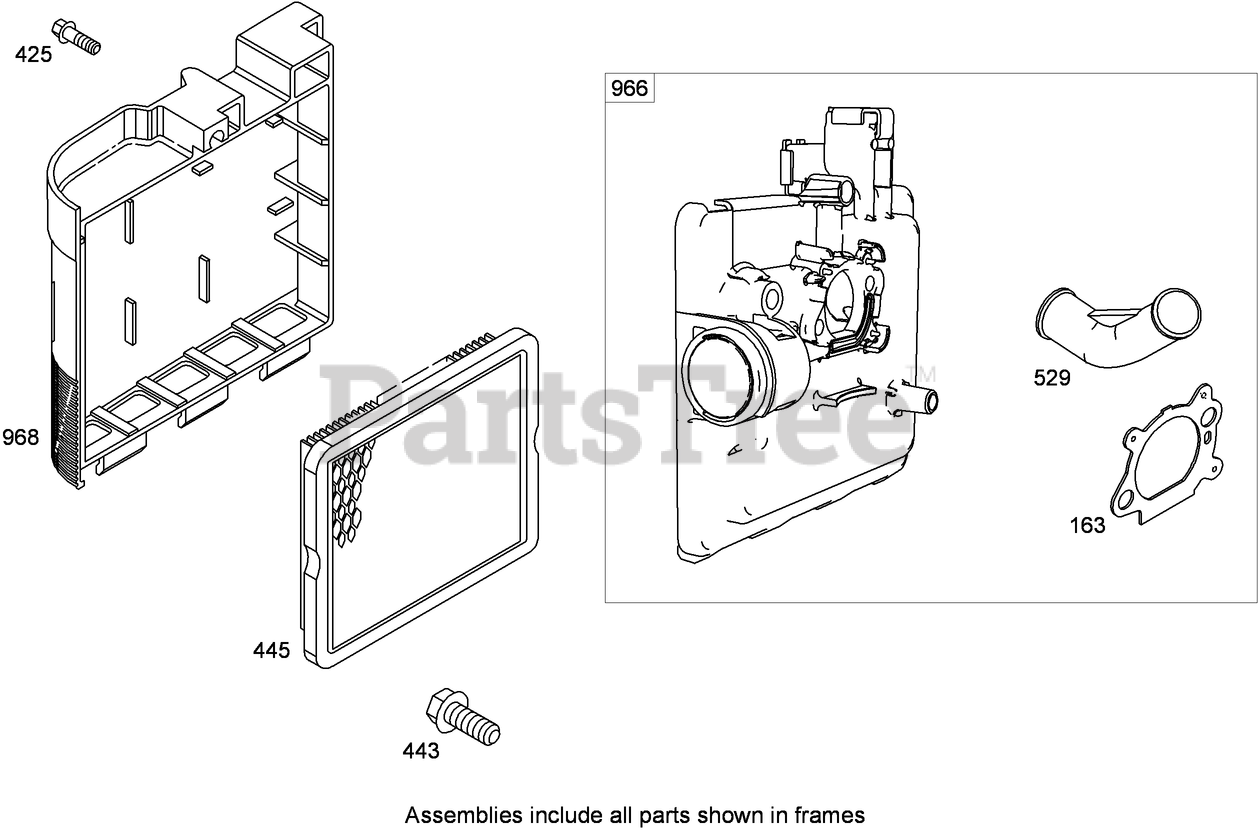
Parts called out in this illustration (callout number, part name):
163	Gasket-Cleaner, Air
425	Screw
443	Screw
445	Filter-Cartridge, Air Cleaner
529	Grommet
966	Base-Primer, Air Cleaner
968	Cover-Cleaner, Air
